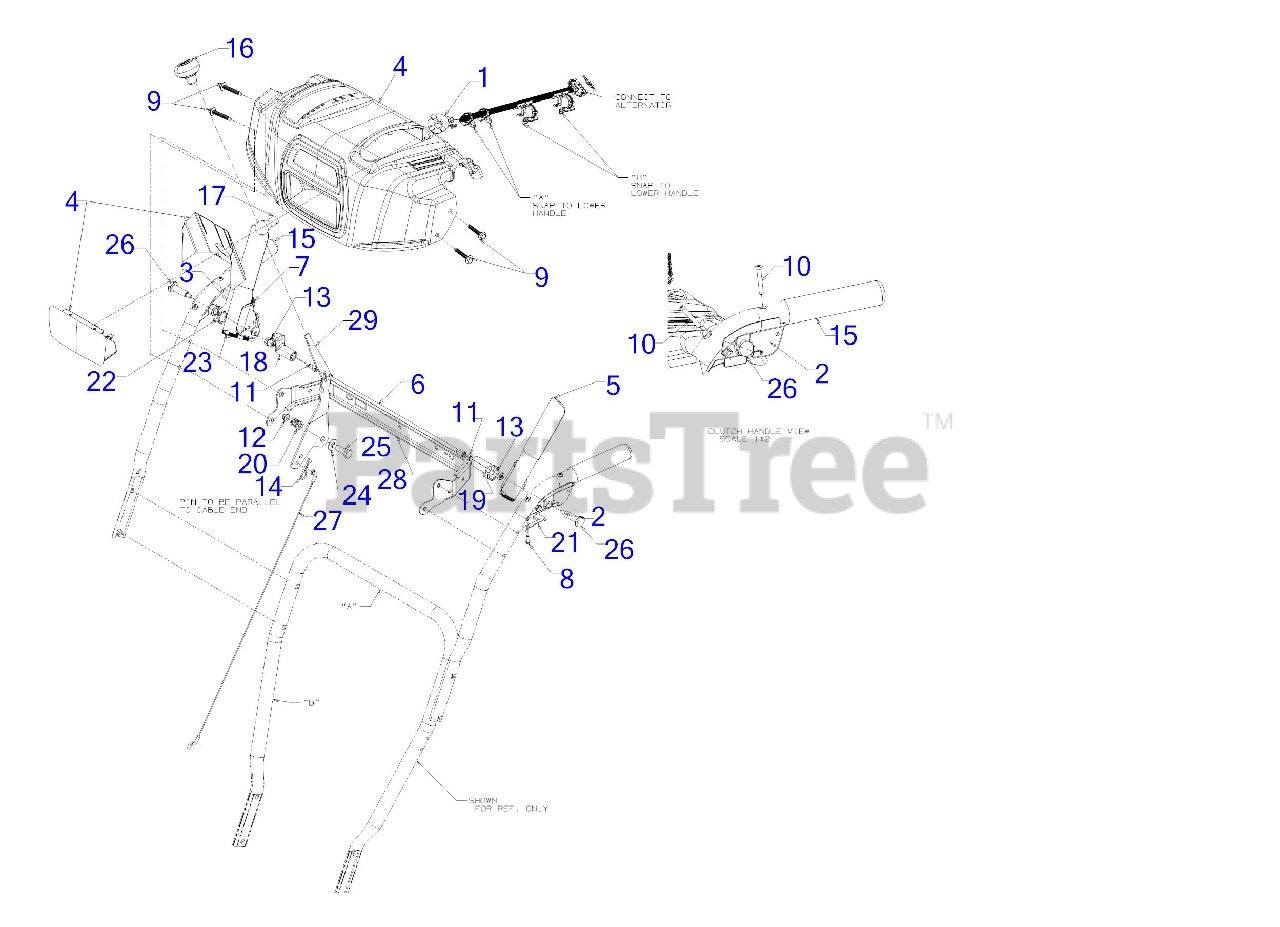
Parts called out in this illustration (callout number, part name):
1	HEADLIGHT SOCKET
1	LIGHT HARNESS
2	CLUTCH LOCK HANDLE ASSEMBLY (LH)
3	CLUTCH LOCK HANDLE ASSEMBLY (RH)
4	HANDLE PANEL ASSEMBLY (CRAFTSMAN)
5	HANDLE ASSEMBLY (LH)
7	ENGAGEMENT HANDLE ASSEMBLY (RH) (BLACK)
8	SCREW #8-16 x .50
9	SCREW 1/4-20 x 1.625
10	SCREW #10-24 x 1.375
11	SCREW 1/4-20 x .50
12	FLANGE LOCK NUT
13	HEX NUT W/PATCH
14	INTERNAL COTTER PIN
16	SHIFT KNOB
17	LAMP-#1683
19	CLUTCH LOCK CAM
20	COMPRESSION SPRING
21	CLUTCH SPRING
22	TORSION SPRING
23	RUBBER BUMPER
24	FLAT WASHER
25	SHOULDER SCREW
26	SHOULDER SCREW .437 x 1.345 1/4-20
27	SPEED SELECTOR CABLE (PLASTIC)
28	HANDLE SUPPORT BRACKET
